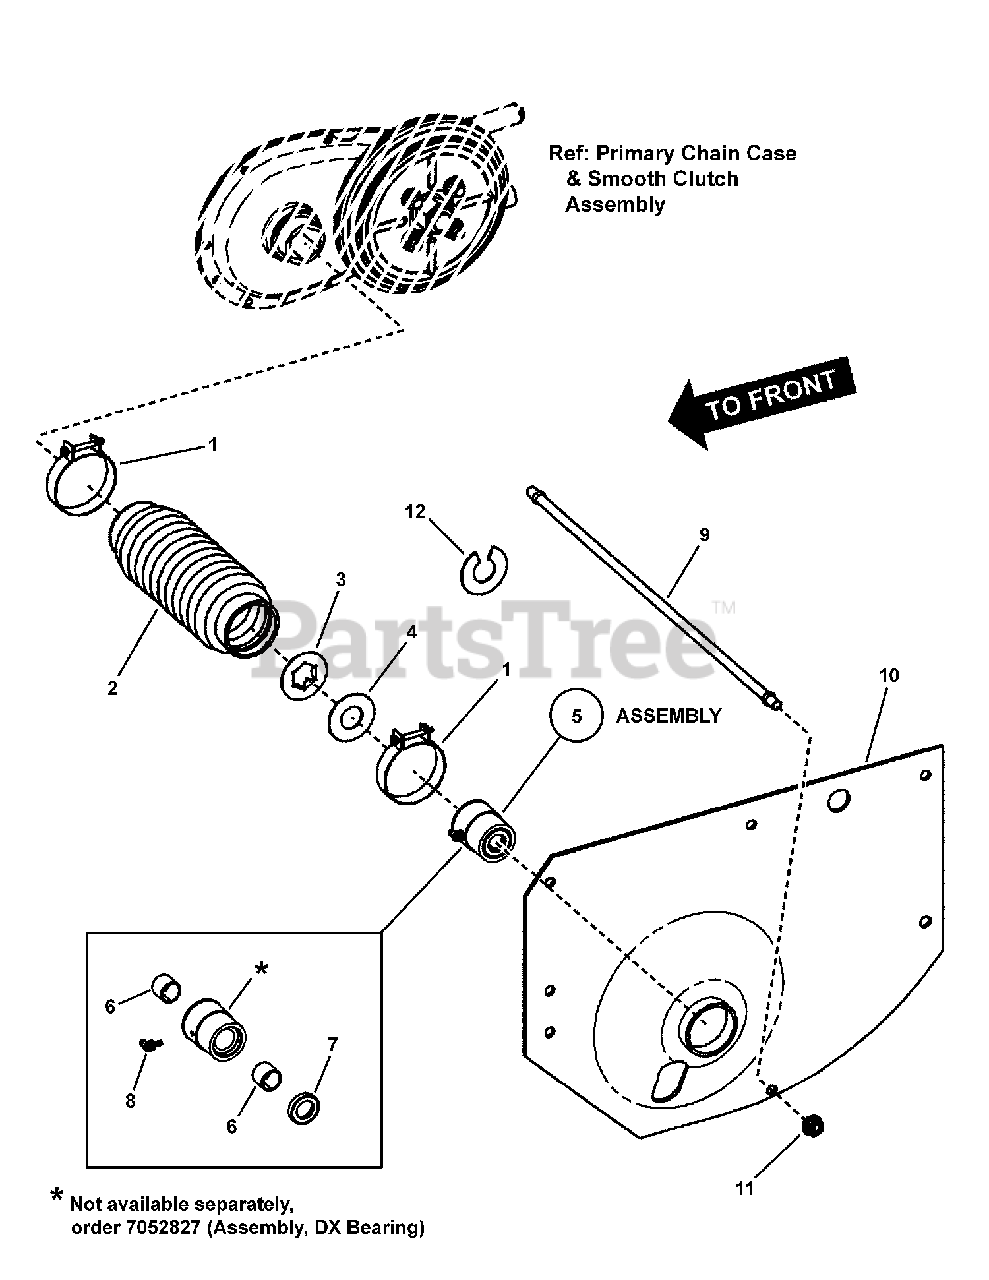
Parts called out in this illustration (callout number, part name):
1	BOOT CLAMP, 2"
2	BOOT, Rear Axle, Thick Flange
3	WASHER, Thrust
4	THRUST WASHER
5	ASSEMBLY, DX Bearing (incl. next 3 items shown below)
6	BEARING, DX
7	SEAL, Axle (Dust/Grease)
8	FITTING, Lube, 45 Degree, 3/16" w/Hex (long shank)
9	TIE ROD (5/16-24 thread - both ends)
10	FENDER, Left Hand (1.628" I. D. Hole)
11	NUT, 5/16-24 Flange Lock (Large)
12	WASHER, Shim
